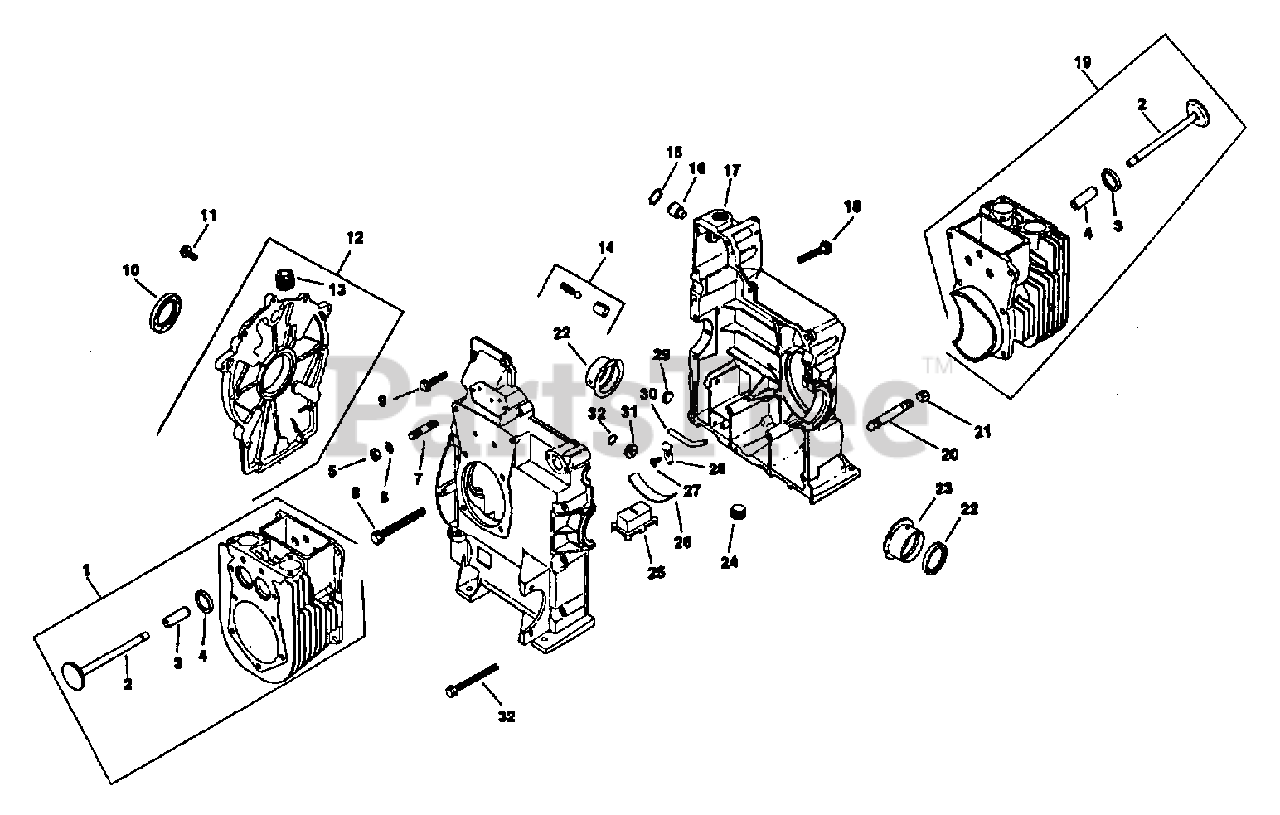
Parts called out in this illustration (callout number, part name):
1	KIT
2	VALVE, EXHAUST
3	GUIDE, VALVE
4	INSERT, VALVE
5	NUT
6	WASHER
7	STUD
8	SCREW
9	SCREW
10	SEAL
11	SCREW
12	KIT, CLOSURE PLATE
13	PLUG
14	KIT, OIL RELIEF
15	RING, RETAINING
16	SHAFT, GOVERNOR
18	SCREW
19	KIT
20	NIPPLE, PIPE
21	CAP, PIPE
22	SEAL, OIL, FRONT
23	BEARING, SLEEVE
24	PLUG
25	HOUSING, OIL PICKUP
26	CLAMP, SPRING
27	SCREW
28	CLAMP, TUBE
29	PLUG, CUP
30	TUBE, DIPSTICK
31	PLUG
32	O-RING
33	SCREW
